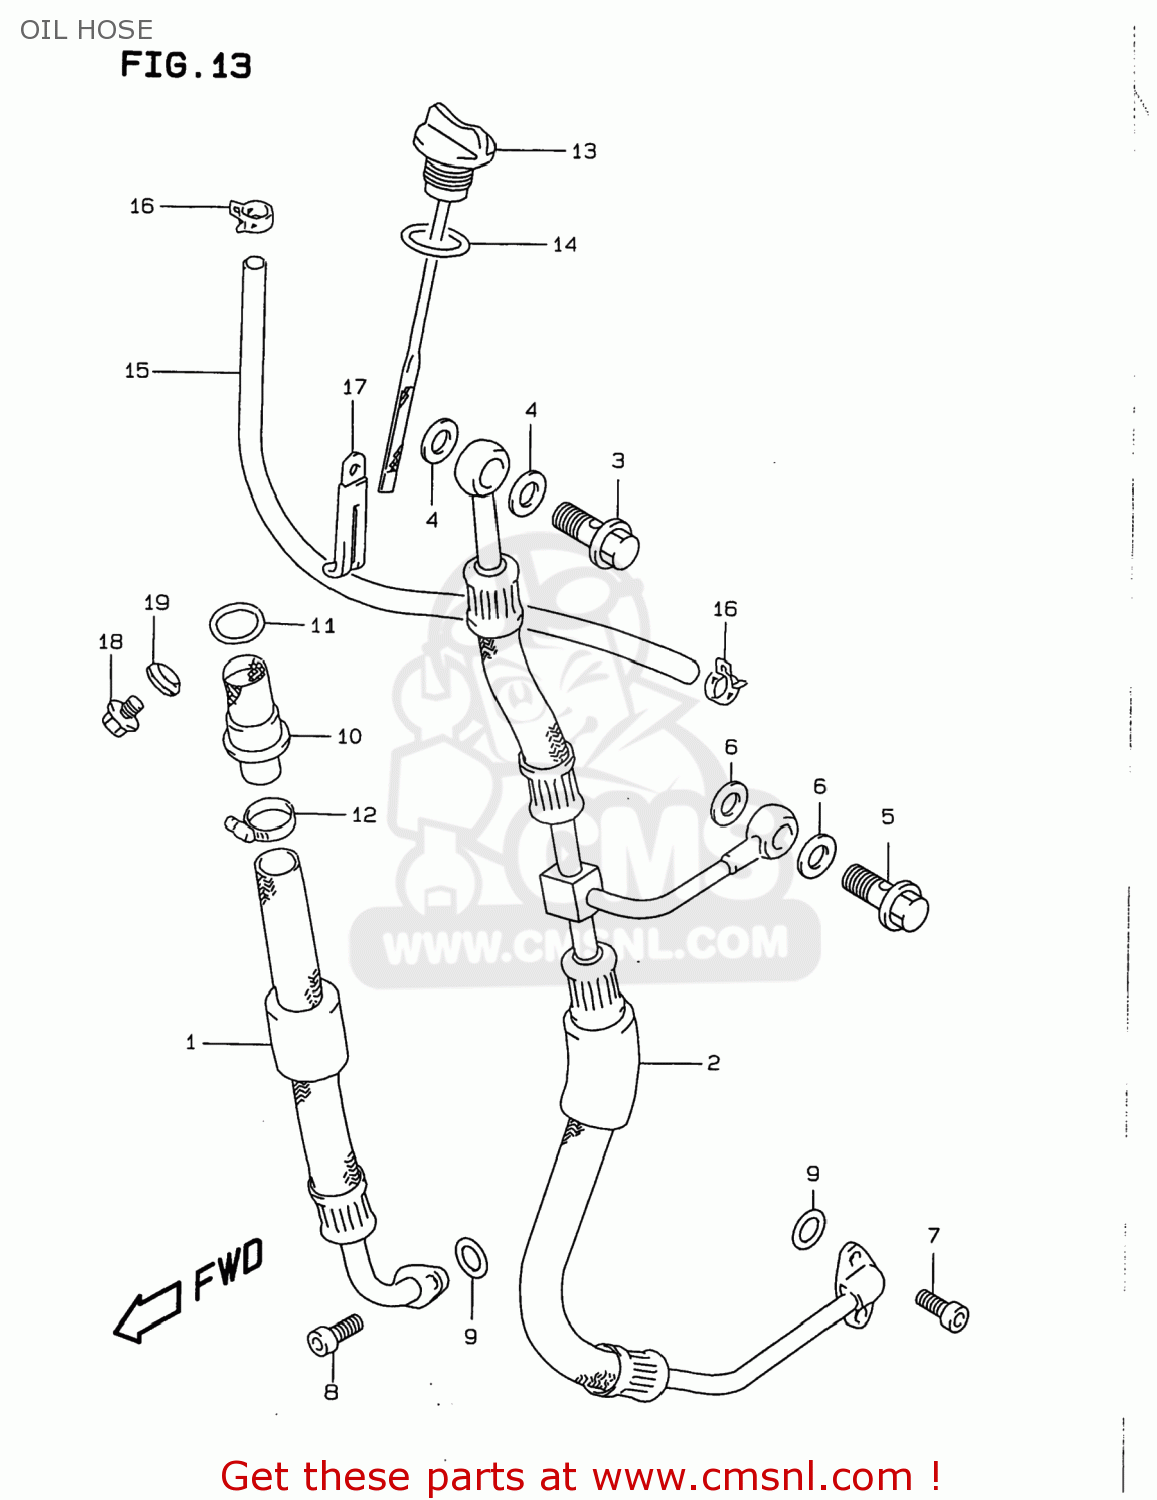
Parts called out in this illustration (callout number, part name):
1	HOSE,OIL TANK INLET
2	HOSE,OIL TANK
3	BOLT UNION
4	GASKET(16X22X2) (NAS)
5	BOLT UNION
6	GASKET(12X17X1) (NAS)
7	BOLT,OIL FILLE
8	BOLT,CRKCASE,R
9	O RING(D:2.4,ID:12.3)
10	STRAINER,FRAME HEAD UNDER
11	O RING(D:3.1,ID:22.7)
12	CLAMP
13	GAUGE ASSY,OIL LEVEL
14	O RING(D:3.1,ID:16.8)
15	HOSE,OIL OVER FLOW
16	CLIP
17	CLAMP(L:45)
18	PLUG(10X12)
19	GASKET(10X14X3.6) (NAS)
